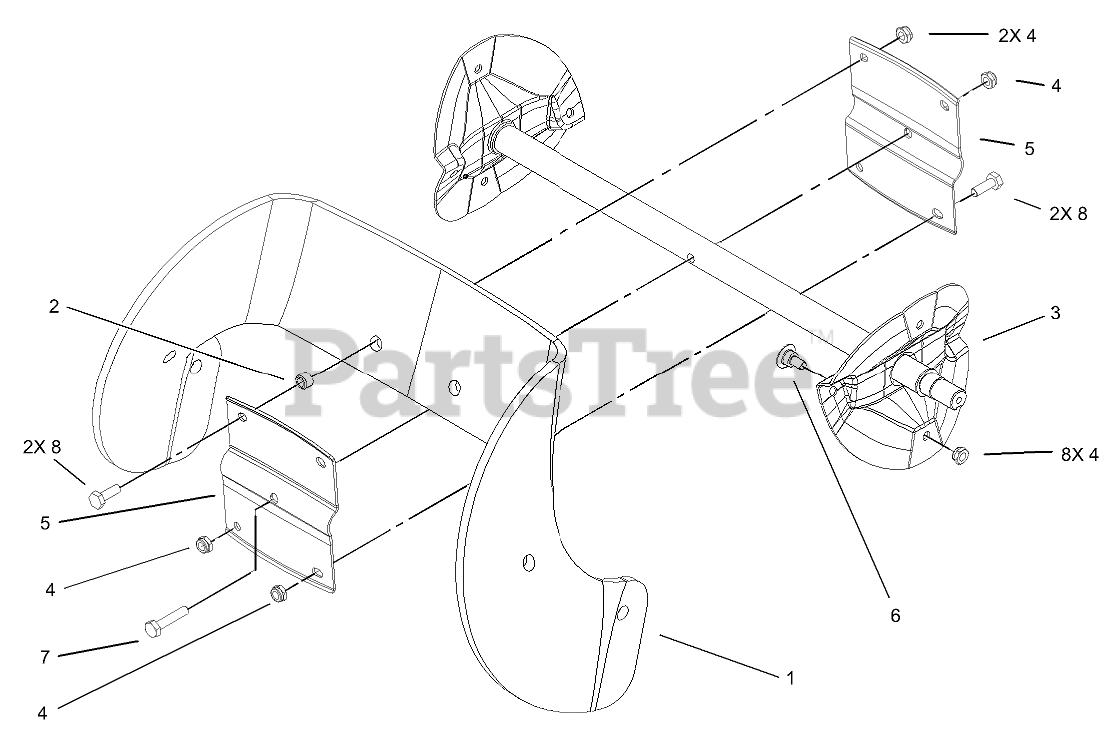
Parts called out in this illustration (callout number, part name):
1	BLADE-ROTOR
2	SPACER-BLADE, ROTOR
3	ROTOR ASM
4	NUT-LOCK, NI
5	HALF-ROTOR
6	SCREW
7	SCREW-HH
8	SCREW-HH
